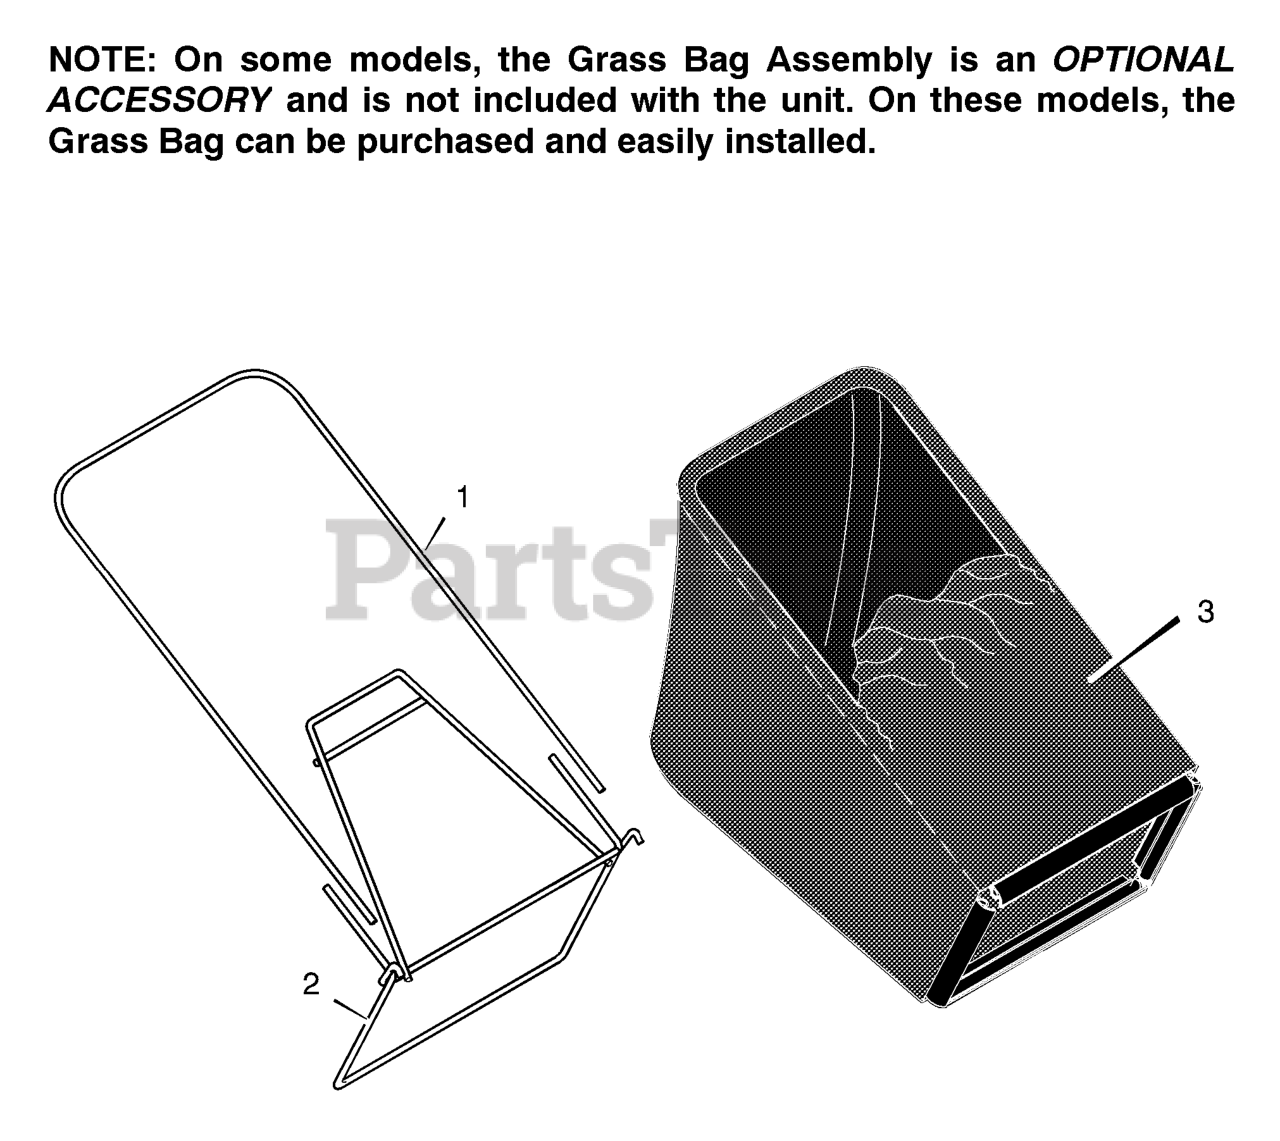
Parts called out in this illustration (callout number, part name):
1	Tube, Bag
2	Frame Assembly
3	Bag, Cloth - Black
